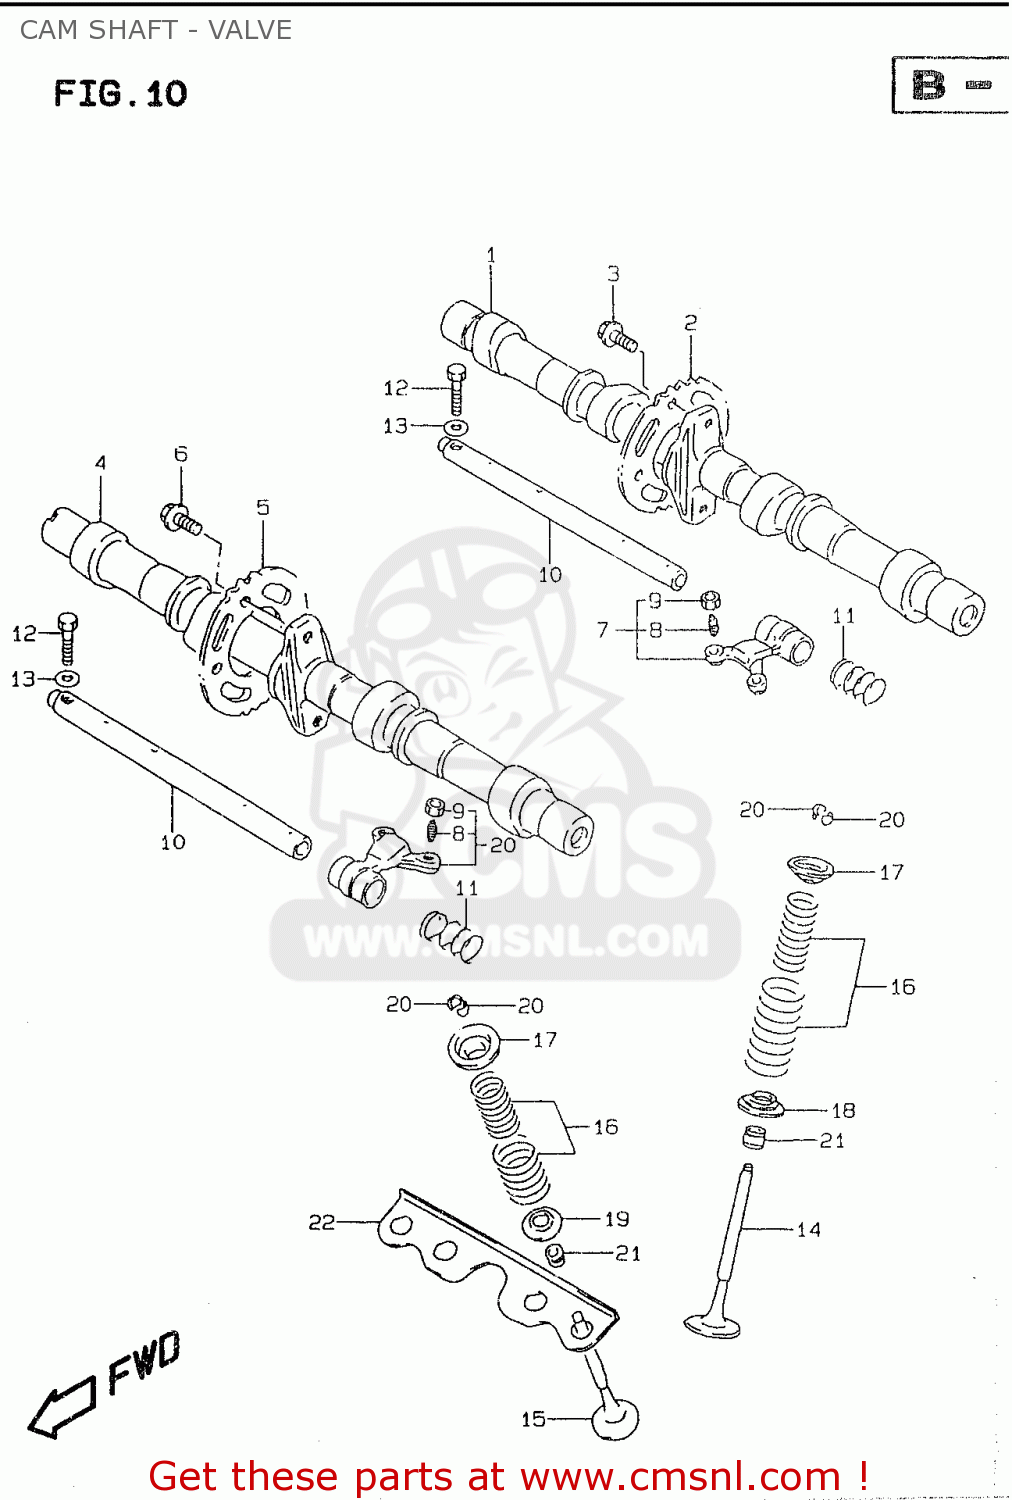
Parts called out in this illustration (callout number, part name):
1	CAMSHAFT,INTAKE
2	SPROCKET,CAMSHAFT
3	BOLT(7X11)
4	CAMSHAFT,EXHAUST
5	SPROCKET,CAMSHAFT
6	BOLT(7X11)
7	ARM,VALVE ROCKER
8	SCREW,TAPPET ADJUSTING
9	NUT,TAPPET ADJUSTING
10	SHAFT,VALVE ROCKER ARM
11	SPRING
12	BOLT
13	WASHER
14	VALVE,INTAKE
15	VALVE,EXHAUST
16	SPRING SET,VALVE
17	RETAINER,VALVE SPRING
18	SEAT,VALVE SPRING
19	SEAT,VALVE SPRING EXH INNER
20	COTTER VALVE
21	SEAL,OIL(5X10X9.7)
22	PLATE,VALVE SEAT
